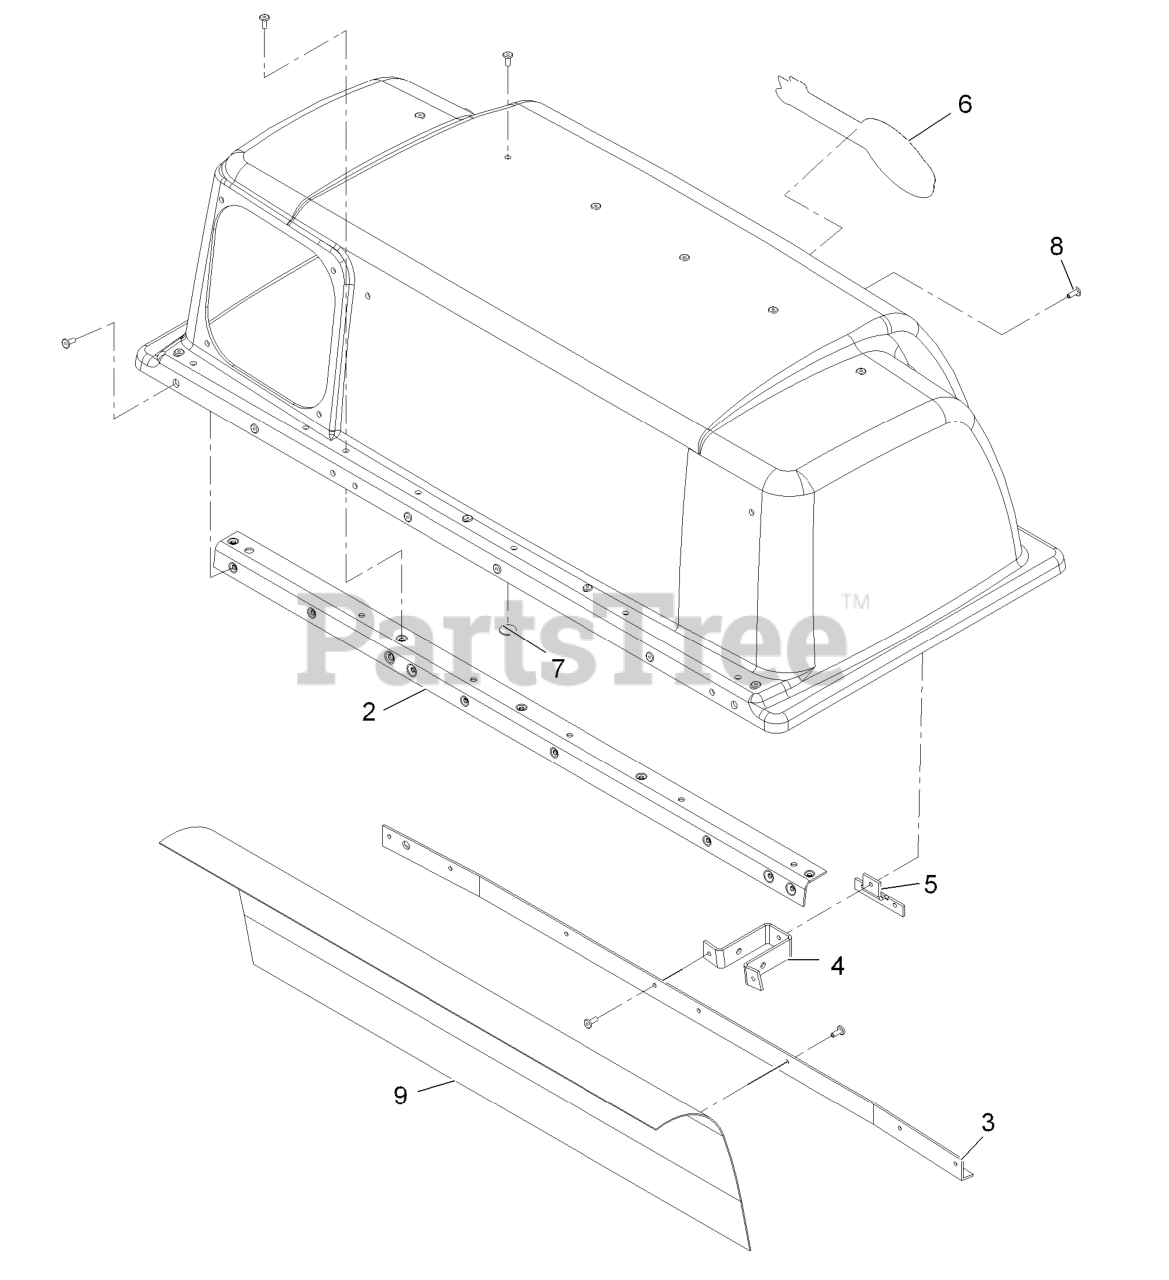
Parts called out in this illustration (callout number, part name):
2	STIFFENER-BAGGER, TOP
3	SUPPORT-SCREEN
4	ANCHOR-LATCH
5	REINFORCEMENT-LATCH
6	DECAL-EXMARK LOGO
7	WASHER-FLAT
8	RIVET-BLIND
9	SCREEN-BAGGER
